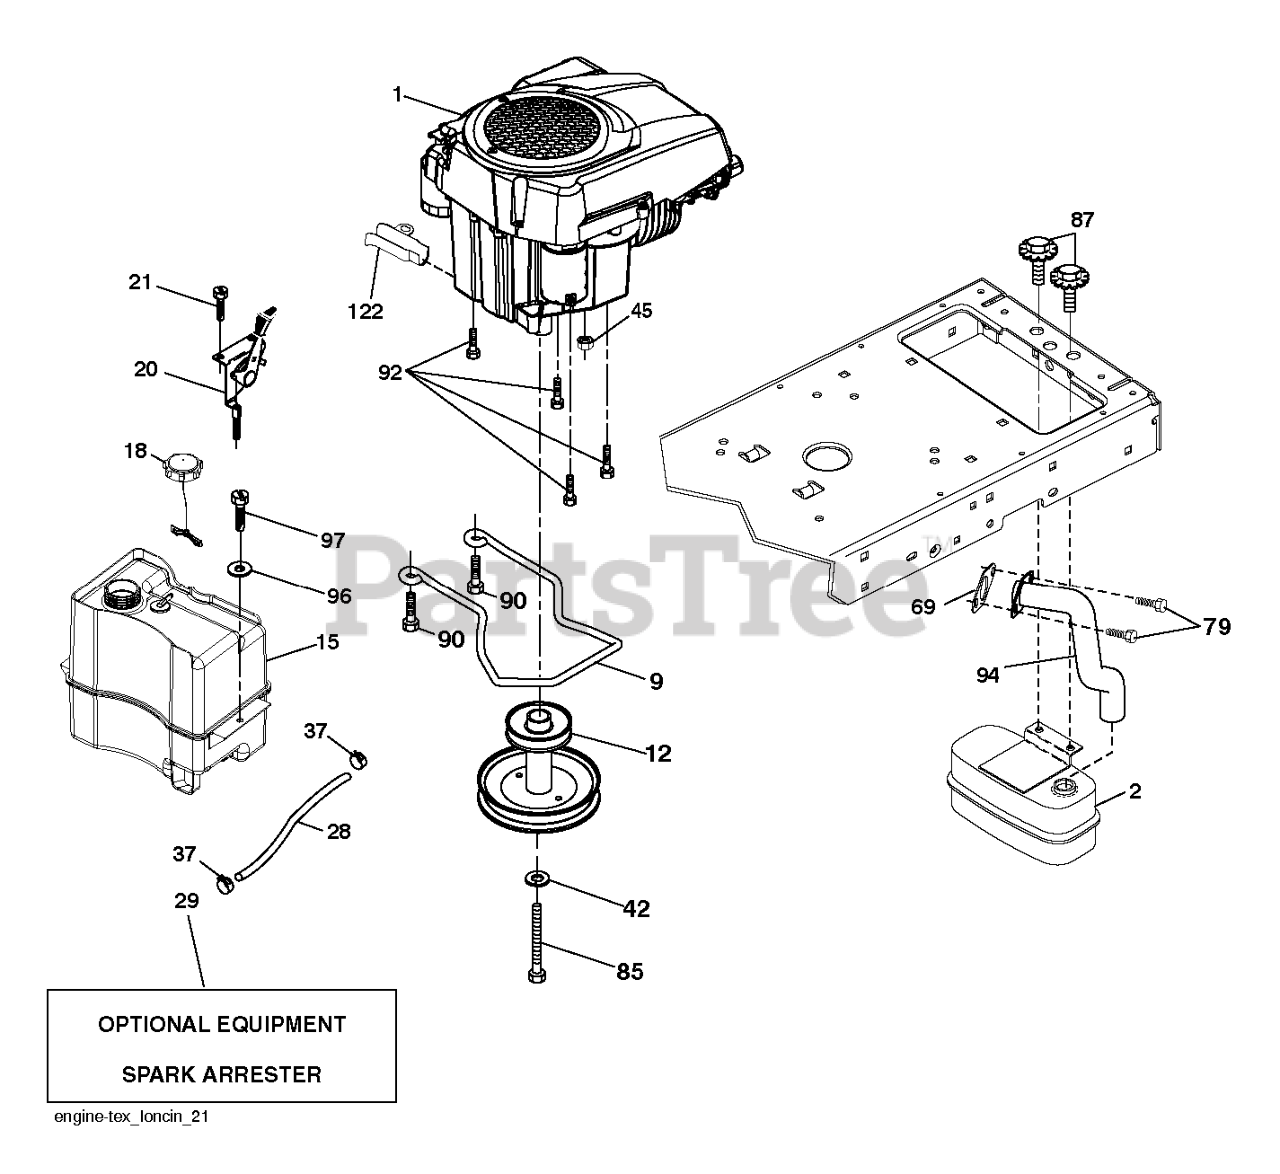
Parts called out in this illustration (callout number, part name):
1	ENGINE.LONCIN.SPARE/452
2	MUFFLER.ASM.SINGLE
9	KEEPER.BELT.ENG.3.25"2BOLT.PNT
12	PULLEY.ENG.CL.MECH.SLVR.LT/YT
15	FUEL.TANK.ASM.NON-EPA
18	CAP ASM.FUEL.2.25"FR.
20	CONTROL.TH/CK.C.
28	LINE.FUEL.20
29	KIT.SPARK ARRESTOR 794945 B&S
37	HOSE CLAMP
45	NUT HEXAGON WITH FLANGE, SERRA
69	GASKET GASKET.EXHAUST.LONCIN 3
85	BOLT.HEX.7/16-20X4.GR5.1.5BLUE
87	BOLT.5/16-18UNCX3/4 W/SEMS.BLK
90	SCREW 3/8-16X1
92	SCREW 3/8-16X1
94	TUBE TUBE.EXHAUST.LONCIN 452.T
97	SCREW HEXWSHR 1/4-20X3/4
122	EXTENSION DRAIN OIL
